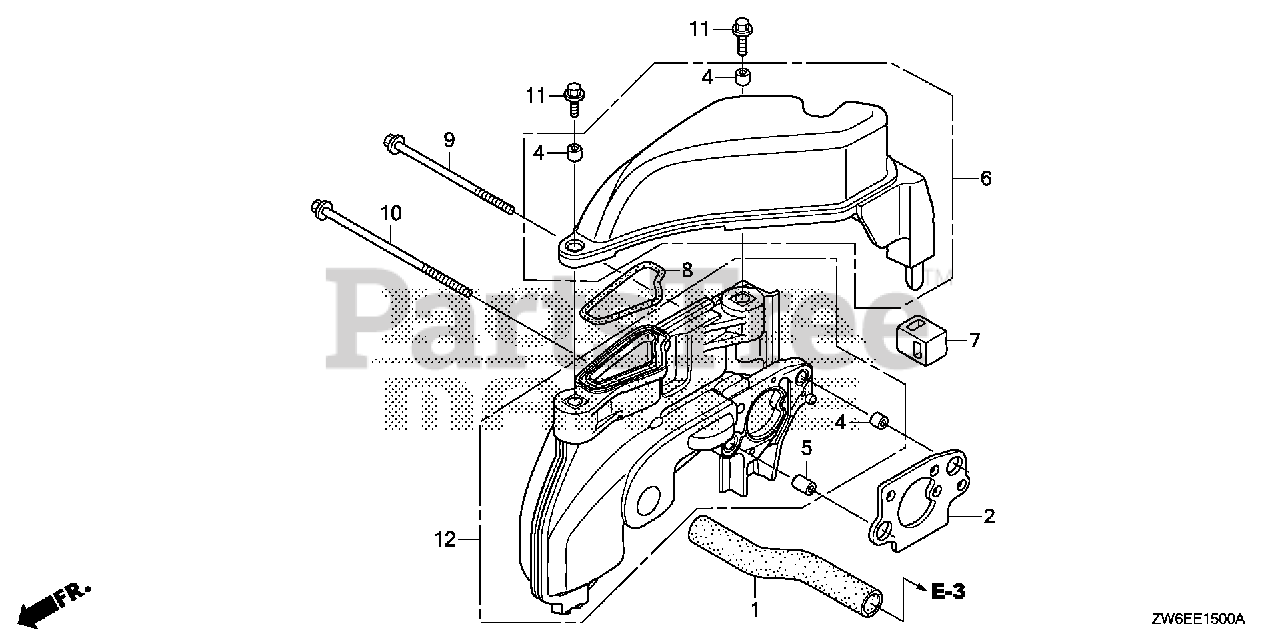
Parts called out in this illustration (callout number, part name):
1	TUBE, BREATHER
2	GASKET, AIR GUIDE
3	GUIDE ASSY., AIR
4	COLLAR, DISTANCE
5	COLLAR, DISTANCE (14MM)
6	CASE, MUFFLER
7	GROMMET, MUFFLER
8	SEAL, MUFFLER
9	BOLT, FLANGE (5X62)
10	BOLT, FLANGE (5X70)
11	BOLT, FLANGE (5X12)
12	GUIDE, AIR INLET
